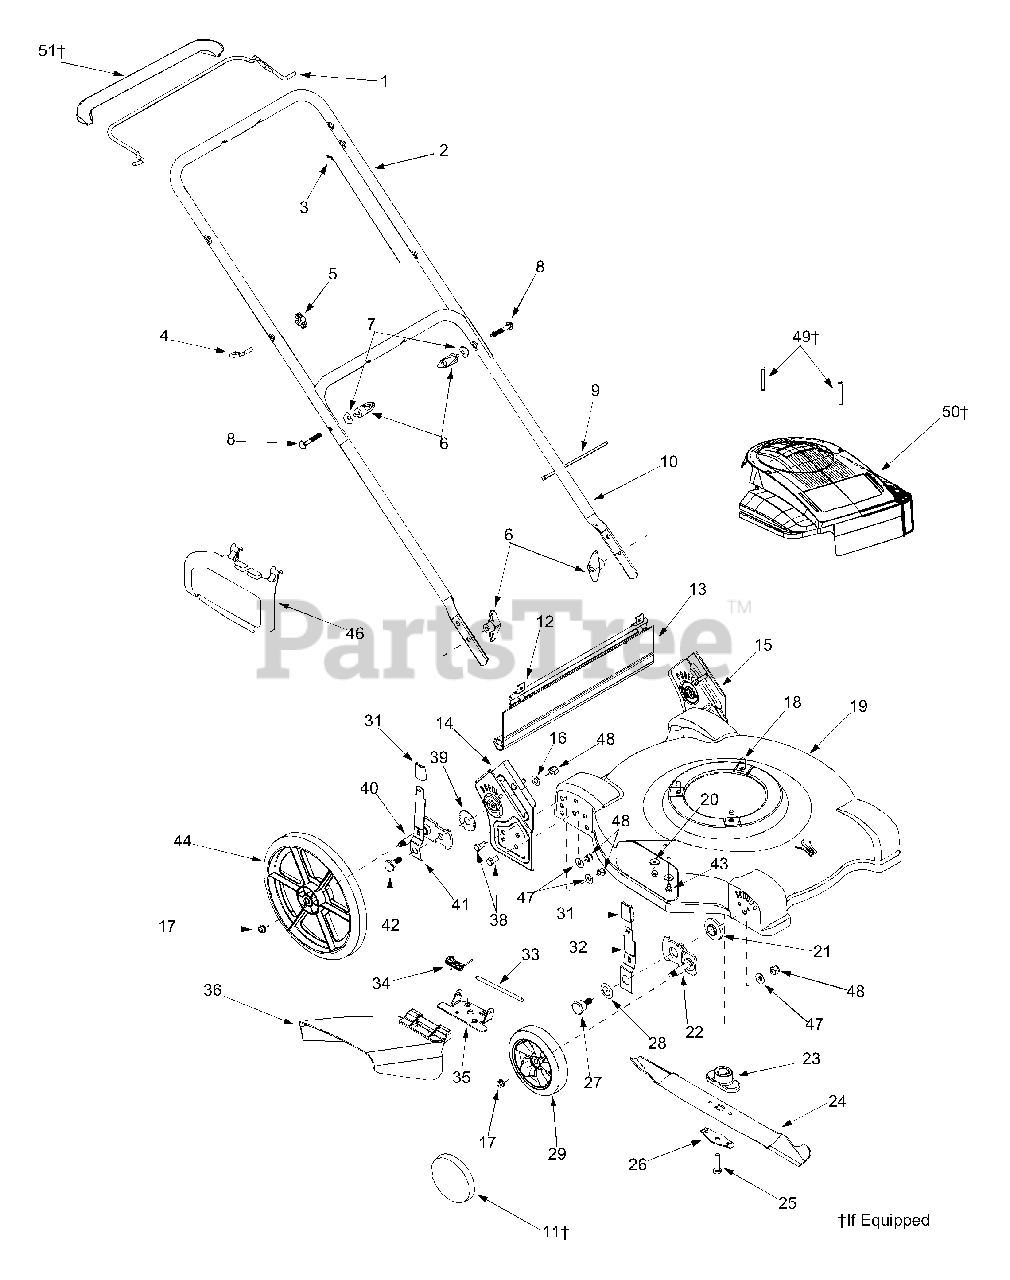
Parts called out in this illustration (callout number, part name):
3	Blade Control Cable - B&S 37.25"
4	Eye Bolt
5	Wing Nut
6	Wing Nut
7	Shoulder Washer.320 ID x.93 OD
8	Carriage Bolt 5/16-18 x 2.0
9	Cable Tie
11	Hub Cap
12	Hinge Clip
13	Trail Shield
17	Lock Nut 3/8 -16
18	Hex Washer Screw 3/8-16 x 1.0
20	Bell Washer.265 x.75
21	Height Adjuster Bearing
22	Pivot Arm Assembly
23	Blade Adapter
24	22" Mulching Blade
25	Hex Cap Screw 3/8-24 x 1.5
26	Blade Bell Support
27	Shoulder Screw 3/8 - 16 x.302
28	Bell Washer.760 ID x 1.25 OD
29	Front Wheel Assembly 7 x 1.8
31	Height Adjuster Knob
32	Front Spring Lever
33	Hinge Pin
34	Torsion Spring
35	Deflector Chute Adapter
36	Side Discharge Chute Assembly
38	Hex Cap Screw 3/8-16 x 1.00
39	Thrust Bearing.688 ID x 1.938 OD
40	Rear Pivot Arm Assembly - RH
41	Rear Spring Lever
42	Shoulder Screw 3/8 - 16 x.442
43	Screw 1/4-20 x.50
44	Rear Wheel Assembly 12 x 1.8
46	Snap Mulching Plug
47	Bell Washer.401 ID x.870 OD
48	Hex Lock Nut 3/8-16
49	Screw #8-18 x 1.25
50	Engine Shroud
51	Deluxe Bail Cover
